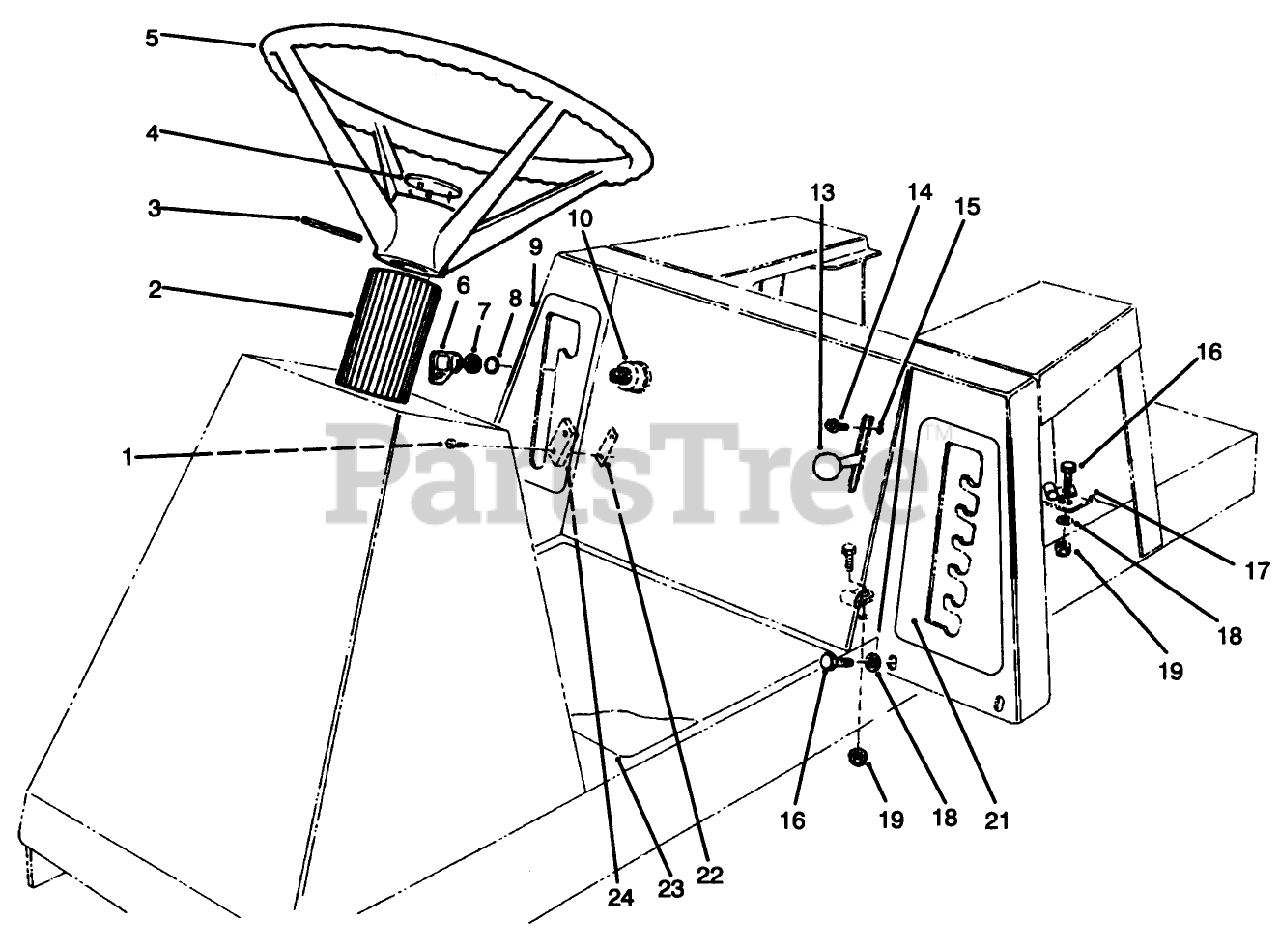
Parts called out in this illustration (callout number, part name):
12	BEARING-NEEDLE
14	BEARING-NEEDLE
15	BEARING-NEEDLE
16	SEAL-OIL
17	OIL SEAL
18	PIN-DOWEL
20	BEARING-NEEDLE
22	SVCBULLT 394
23	SVC BULLT 394
24	GEAR-PINION, 11T
25	PIN-DIFFERENTIAL
26	AXLE GEAR
29	BEARING-NEEDLE
33	GEAR
34	RAIL-SHIFT
35	RAIL-REAR SHIFT
36	FORK-SHIFT
37	BALL-DETENT
39	PIN-SHIFT
40	CUP-PLUG
42	BUSHING-BRONZE
43	GEAR-CLUSTER SHAFT
45	GEAR/BUSHING ASM-REVERSE IDLER
46	BUSHING
48	PINION SHAFT
49	WASHER-THRUST
52	GASKET-TRANSMISSION
54	SETSCREW
55	COVER-DUST
56	SHIFT KNOB
